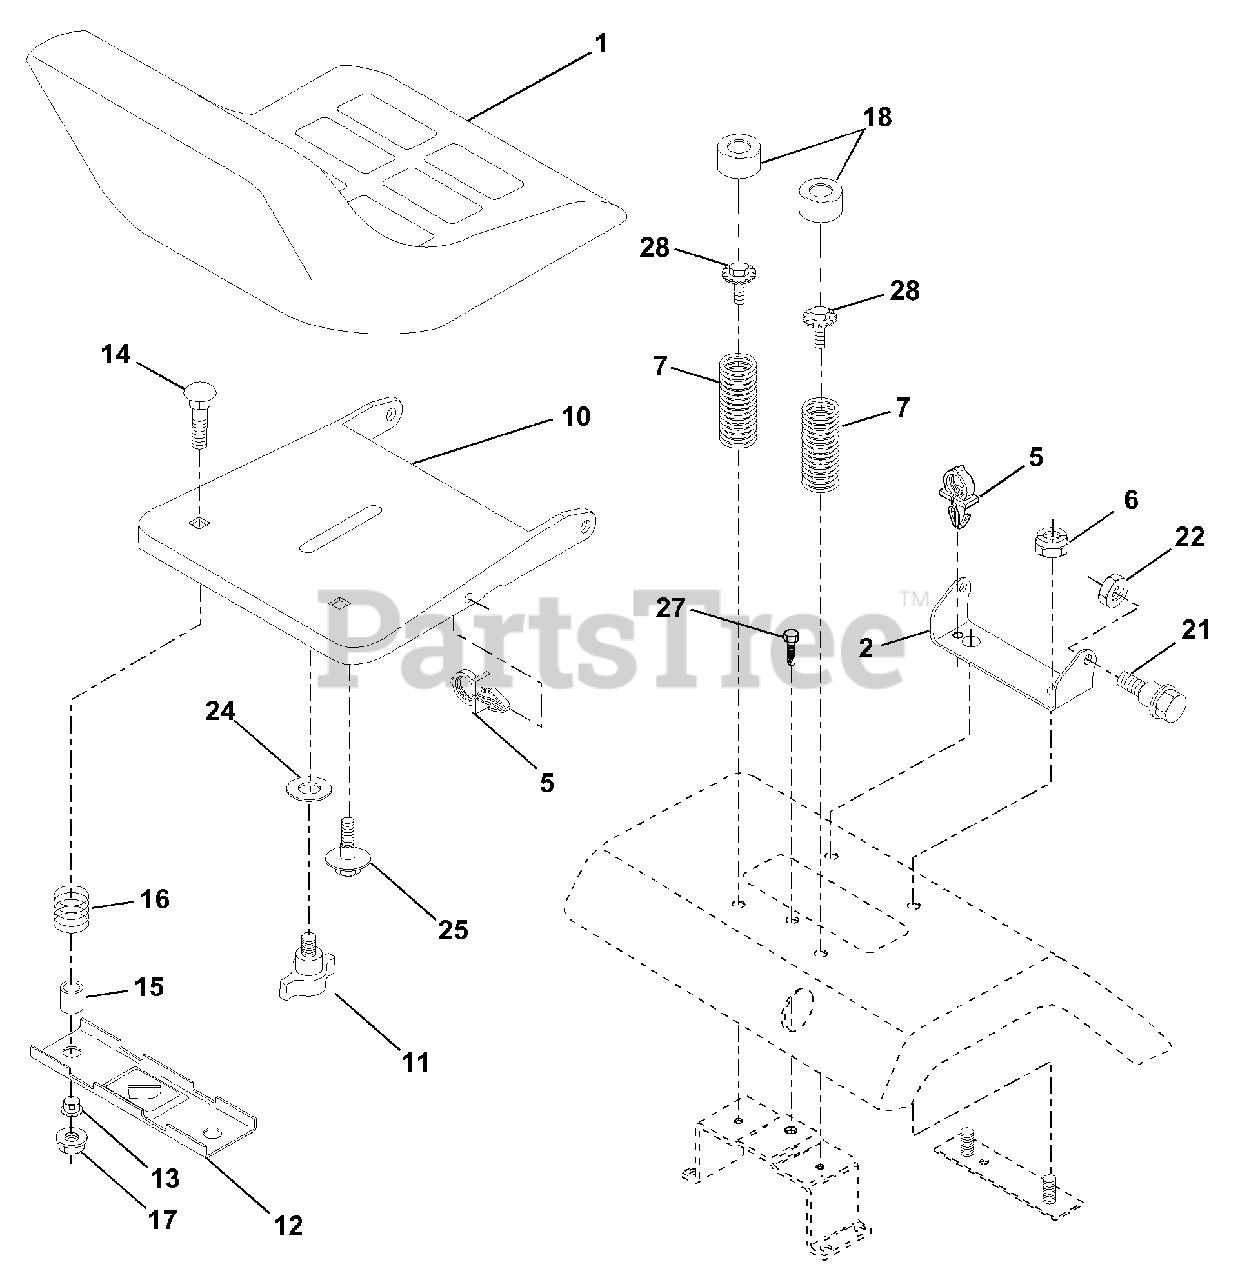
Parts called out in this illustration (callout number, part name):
2	Bracket Pivot Seat 8 720
5	Clip Push-In
6	Nut Hex w/Ins. 3/8-16 Unc
7	Spring Seat Cprsn 2 250 Blk Zi
10	Pan Seat
11	Knob Seat Adj. Wingnut
12	Bracket Mounting Switch
13	Bushing Snap Blk Nyl 50 Id
14	Bolt Rdhd Sqnk 1/4-20 x 1-1/2
15	Spacer Split 28 x 88
16	Spring Cprsn
17	Nut Lock 1/4 Lge Flg Gr 5 Zinc
18	Cap Spring Seat
21	Bolt Shoulder 5/16-18 Unc
22	Nut Hex Lock W/Ins 5/16-18
24	Washer 17/32 X 1-3/16 X 12 Ga.
25	Bolt Shoulder 5/16-18 X 62
27	Screw Thdrol 3/8-16 x 1/2
28	Bolt 5/16-18 Unc x 3/4 w/Sems
